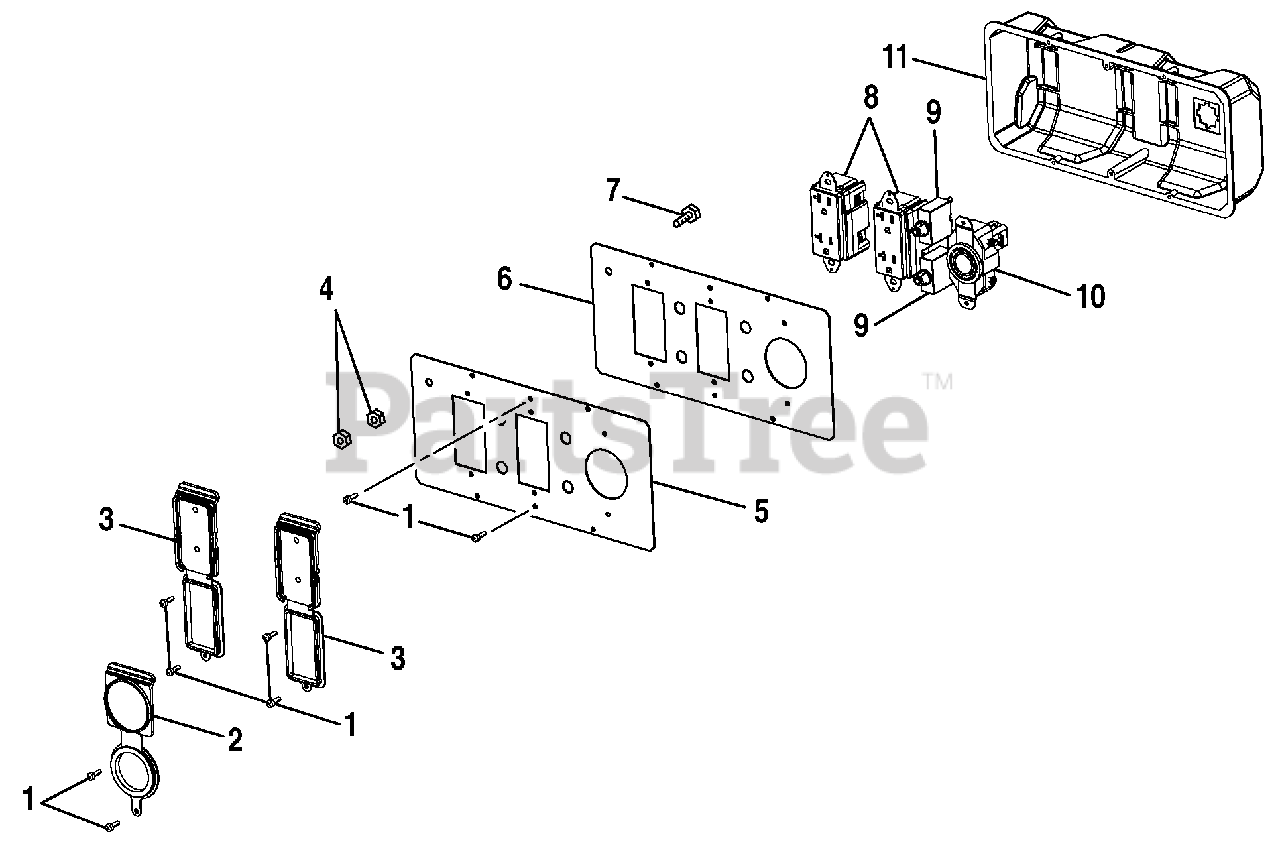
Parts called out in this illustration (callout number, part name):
1	Screw (6-20 x 3/8 in.)
2	Outlet Cover (240 Volt)
3	Outlet Cover (120 Volt)
4	Hex Nut (1/4-20)
5	Electrical Outlet Label
6	Cover Plate
7	Screw (1/4-20 x 5/8 in., Hex Hd.)
8	Duplex Receptacle (120 Volt)
9	Circuit Breaker (20 Amp, 125 Volt)
10	Twist Lock Receptacle (120/240 Volt, 20 Amp)
11	Rear Control Panel
